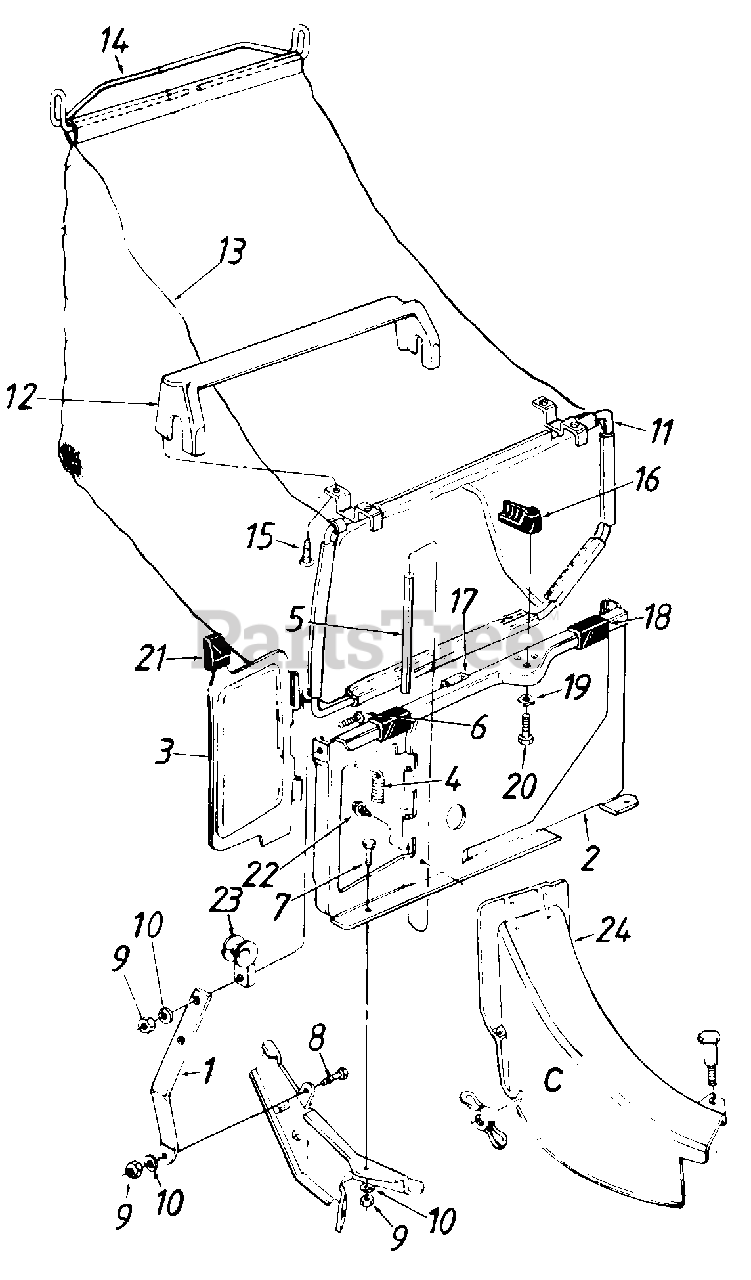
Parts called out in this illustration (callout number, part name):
1	Panel Support Brkt.
2	Top Catcher Panel Ass'y.
3	Top Discharge Door
4	Torsion Spring
5	Pivot Pin
6	Truss Mach. Scr. 1/4-20 x .75" Lg.
7	Hex Bolt 1/4-20 x .50" Lg.
8	Hex Bolt 1/4-20 x .62" Lg.
9	Hex Nut 1/4-20 Thd.
10	L-Wash. 1/4" I.D.
11	Front Grass Catcher Frame
12	Grass Catcher Handle
13	Grass Bag
14	Upper Bag Handle
15	Hex AB-Tap Scr. #12 x 1.0"
16	Grass Catcher Locking Knob
17	Foam Strip 1" Lg.
18	Panel Clip
19	Spring Wash. .32" I.D.
20	Hex Bolt 1/4-20 x .62" Lg.
21	Door Grip
22	Hex B-Tap Scr. #10 x .38"
23	Rope Guide
24	Top Discharge Chute Ass'y.
